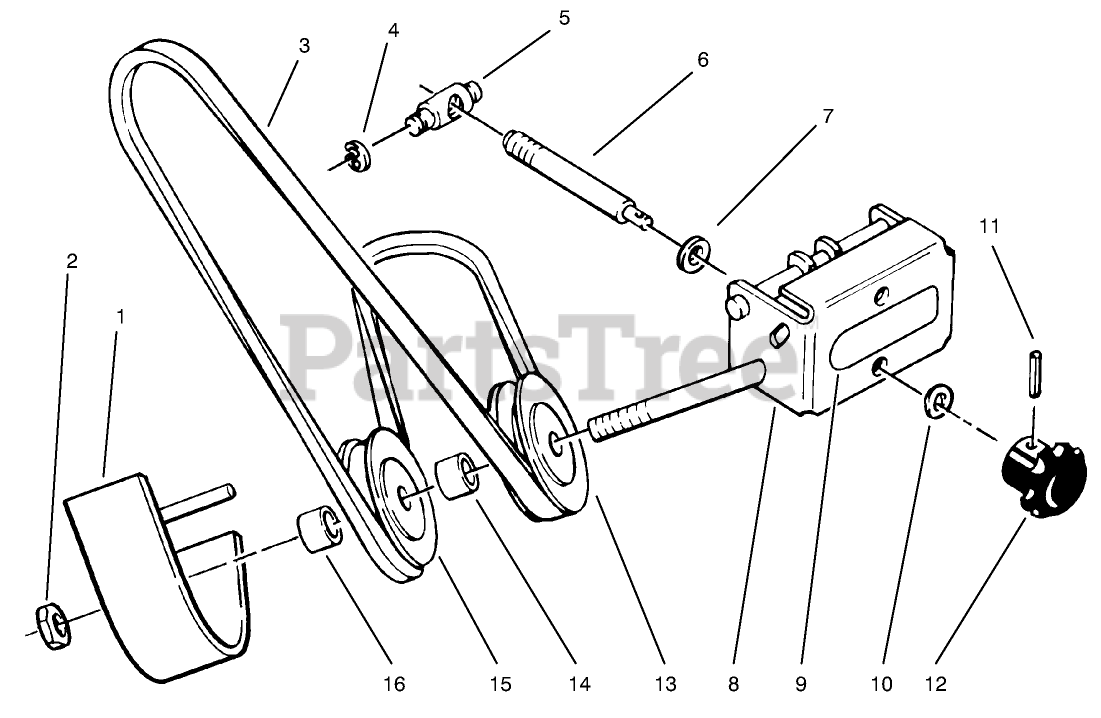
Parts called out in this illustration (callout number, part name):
1	COVER WA - BELT
2	NUT
3	V-BELT
4	RING-RETAINING
5	TRUNNION-DOUBLE
6	ROD ADJ
7	WASHER-FLAT
8	WA FRONT SUPPORT
9	DECAL-ATTACH A-MATIC
10	WASHER-SPRING
11	PIN-ROLL
12	KNOB-ADJUSTMENT
13	PULLEY-IDLER
14	SPACER
15	PULLEY-FLAT IDLER
16	SPACER-OUTER
